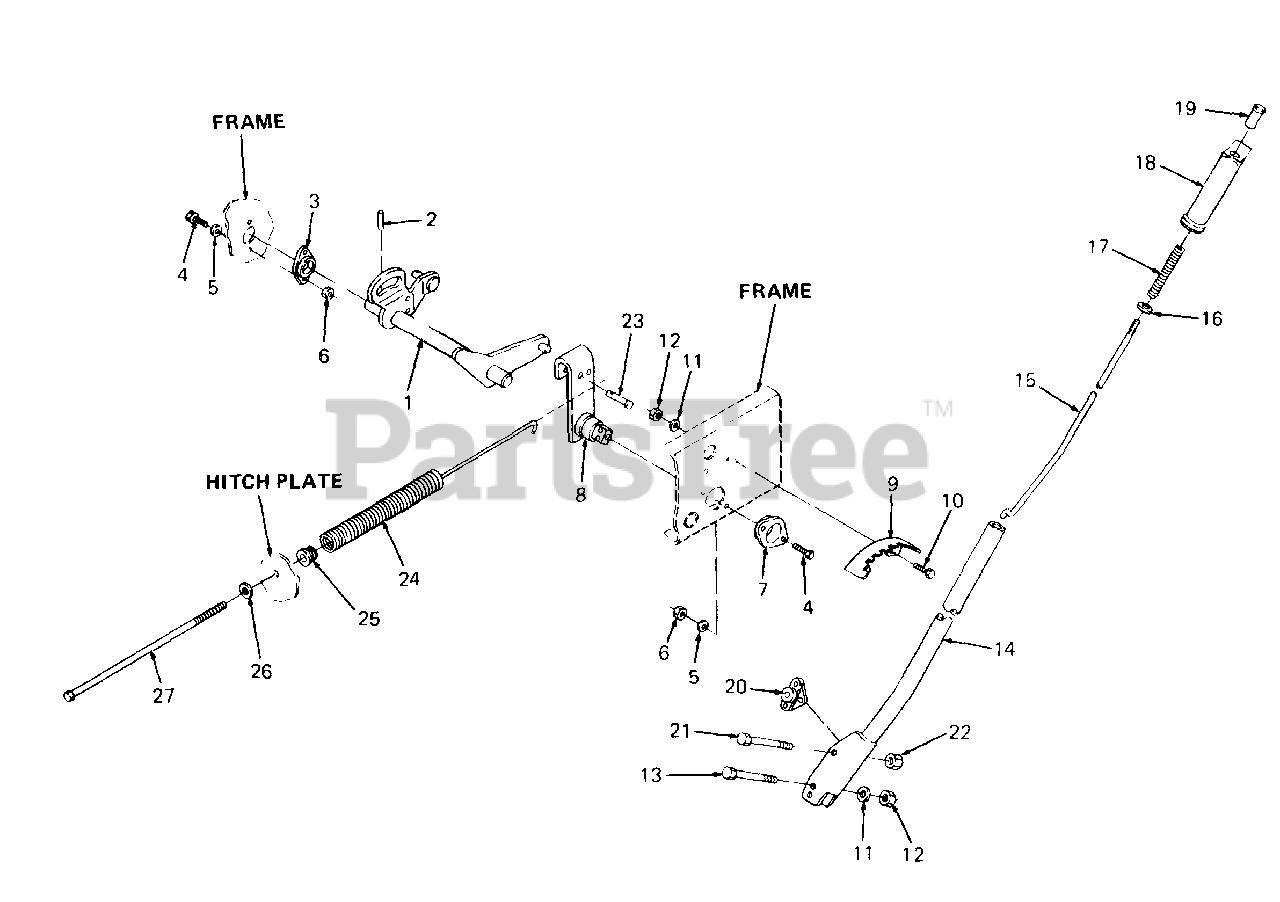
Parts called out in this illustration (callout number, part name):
3	Bushing, Lift, LH
4	Screw, Hex Cap, 1/4-20 X .75 Lg GR5
5	Washer, Lock, 1/4
6	Nut, Hex, 1/4-20
7	Bushing, Lift, RH
8	Bracket Assy, Lift
10	Screw, Hex Cap, 5/16-18 X .62 Lg
11	Washer, Lock, 5/16
12	Nut, Hex, 5/16-18
13	Screw, Hex Cap, 5/16-18 X 1.75 Lg GR5
16	Washer, Flat, .260 X .720 X .06 Thk
17	Spring, Lift Handle
18	Grip, Lift Handle
19	Button, Handle
20	Kit, Index Pawl
21	Screw, Hex, 3/8-24 X 1.62 Lg
22	Nut, Hex Center Lock Jam, 3/8-24
23	Pin, Clevis, 1/2 Dia X 2.19 Lg
24	Spring, Lift Assist, 1.03 ID X 17.0 Lg
25	Insert, Spring
26	Washer, Flat, .385 X .62 X .063 Thk
27	Screw, Hex Cap, 3/8-16 X 13.0 Lg
